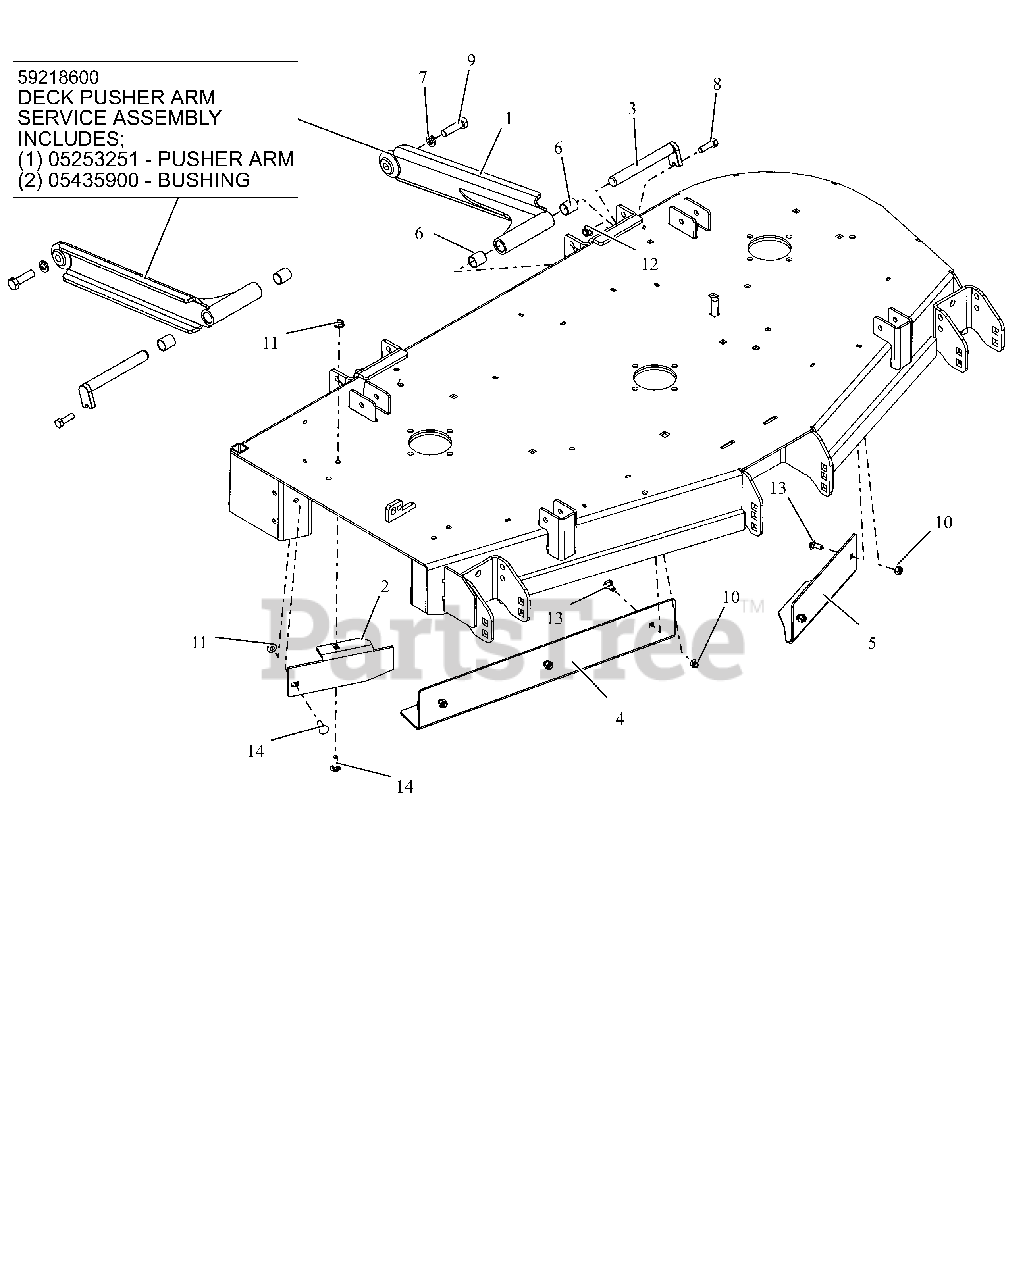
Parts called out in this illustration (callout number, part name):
1	WLDMT, DECK STABILIZER ARM (BLACK)
1	DECK STABILIZER ARM W/BUSHINGS
2	52" DISCHARGE BAFFLE - RED
3	PIN, MOWER MTG
4	BAFFLE, 52" RH VACUUM (RED)
5	BAFFLE, 52" LH VACUUM (RED)
6	BRG, .750 X .875 X 1.000
7	WSHR,LK-REG .500X.125 ZCC
8	BLT, HEX .38-16X1.25 G5 ZCC
9	BLT, HEX 0.5-13X1.75 GR5 ZCC EP80
10	NUT,NYL .31-18 G5 ZCC
11	NUT,NYL-FLG .31-18 GF ZCC
12	NUT,NYL-FLG .38-16 GF ZCC
13	BLT,RHSN .31-18X.75 G5 ZCC
14	BLT,RHSN .31-18X1.00 G5 ZCC
